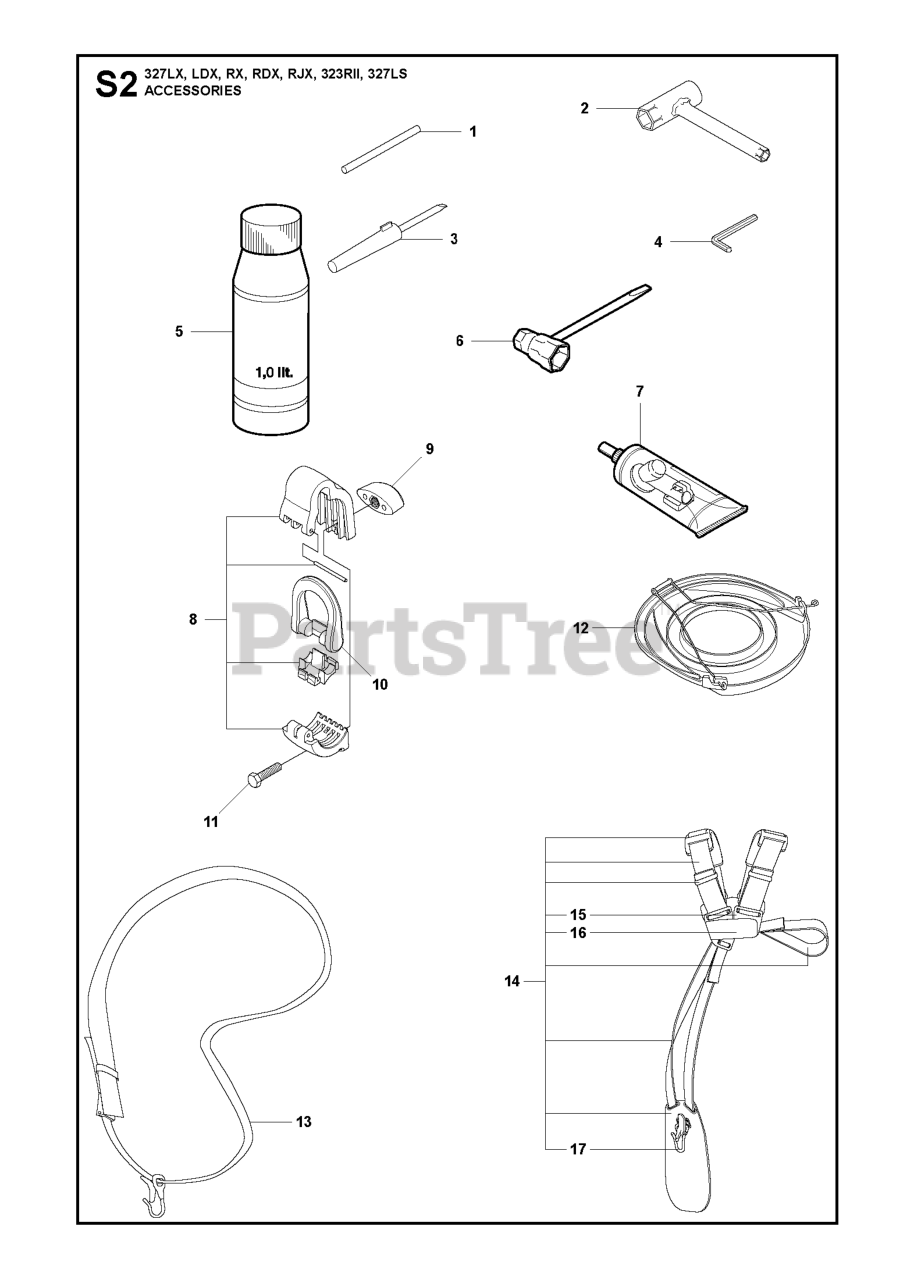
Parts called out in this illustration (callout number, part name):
1	LOCKING PIN
2	COMBI WRENCH
3	SCREWDRIVER
4	L-KEY WRENCH
5	Air Filter Oil 1l.
6	COMBI TOOL
7	BEVEL GEAR GREASE
8	HANGING BRACKET
11	SCREW M6S 5X20
12	BLADE GUARD TRANSPORT
13	Harness-w/o warning
13	Harness - Diagonal with sign
14	Harness w/warning
14	HARNESS DUO
17	HOOK, CPL.
